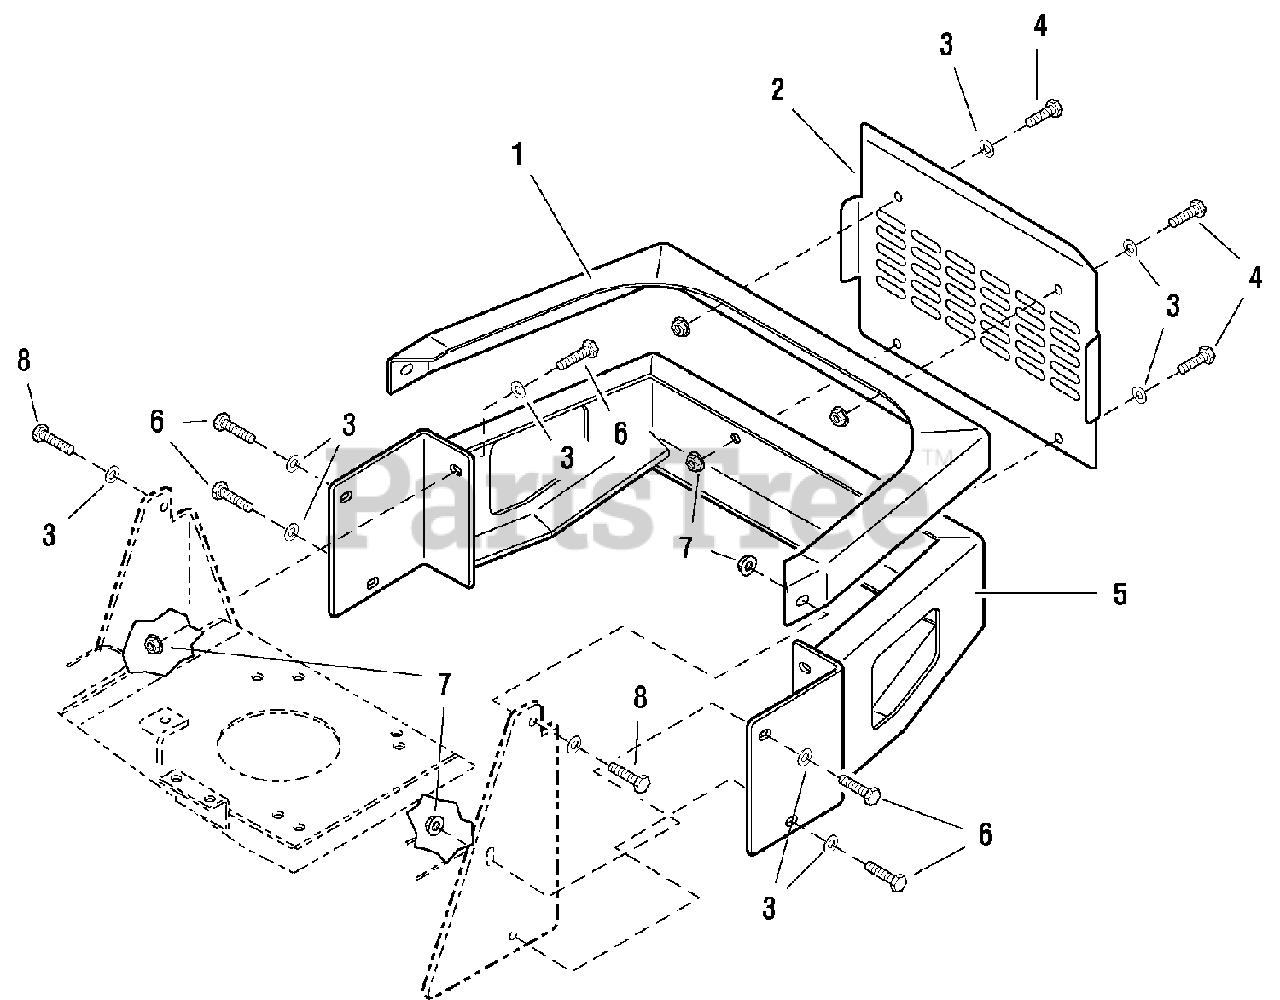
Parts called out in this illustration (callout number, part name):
1	TOP BUMPER
2	BUMPER SHIELD
3	WASHER, SAE, 5/16
4	BOLT, 5/16-18 X 3/4 GD5
5	LOWER BUMPER
6	CAPSCREW, Hex Head, 5/16-18 x 1-1/4
7	NUT, Hex Serrated Flange, 5/16-18
8	CAPSCREW, Hex Head, 5/16-18 x 1
